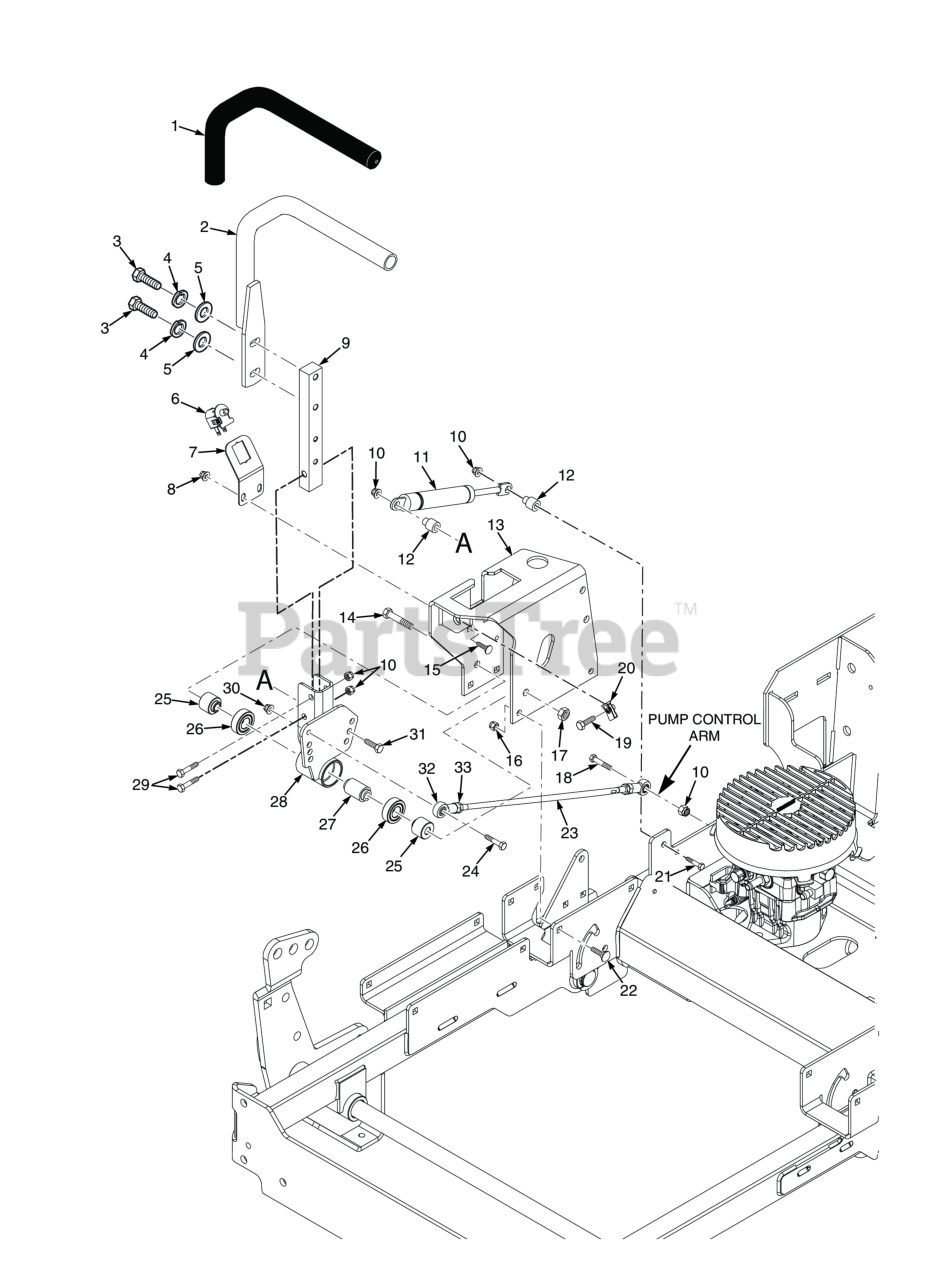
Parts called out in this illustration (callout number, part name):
1	Grip, Control Handle
2	Handle Bar w/Grip
3	Bolt, Hex Head 3/8-16 x 1-1/4", Kawasaki FX / FT & FT-EFI
4	Lockwasher, 3/8" Spring, Kawasaki FX / FT & FT-EFI / B&S 32BV
5	Flatwasher, 3/8" Special (.391 x .938 x .105)
6	Switch, Interlock, Normally Open
7	Bracket, Operator Presence Switch
8	Nut, Flanged Elastic Stop 1/4-20
9	Bar, Control Lever
10	HEX NUT, ELASTIC STOP LOCK, 5/16-18
11	Gas Damper
12	Spacer, Pump Dampener
13	Control Plate w/decal, LH
14	Bolt, Hex Head 3/8-16 x 4-1/4"
15	Serr. Fl. Hex Head CPSCR, 1/4-20 x 3/4"
16	Nut, Serrated Flange 5/16-18 (Right Front Engine Mounting, Briggs and Kohler Only)
17	Bolt, Hex Head 3/8-16 x 1" Ser. Flg.
18	Bolt, Heax Head 5/16-18 x 1" (48V / 52V)
19	Bolt, Hex Head 3/8-16 x 1-1/4" with Thread Lock Patch
20	U-Nut, 3/8-16 (short)
21	Bolt, Hex Head 5/16-18 x 1-1/2" (Right Front Engine Mounting, Briggs and Kohler Only)
22	Bolt, 5/16-18 x .75 RHSN Carriage
23	Linkage Assy, Steering
24	Bolt, Hex Head, 1/4-20 x 1-1/2"
25	Spacer, Controls
26	BEARINGS, BALL, NEUTRAL RETURN
27	Spacer, Bearing
28	Pivot Weldment, Control Arm RH
29	Bolt, Hex Head 5/16-18 x 1-1/2" - Front
30	HEX, NUT, ELASTIC STOP LOCK, 1/4-20
31	Bolt, Hex Head 5/16-18 x 1-1/2" (Right Front Engine Mounting, Briggs and Kohler Only)
32	Rod End, 5/16-24 RH
33	Nut, 5/16-24 UNF Jam LH
